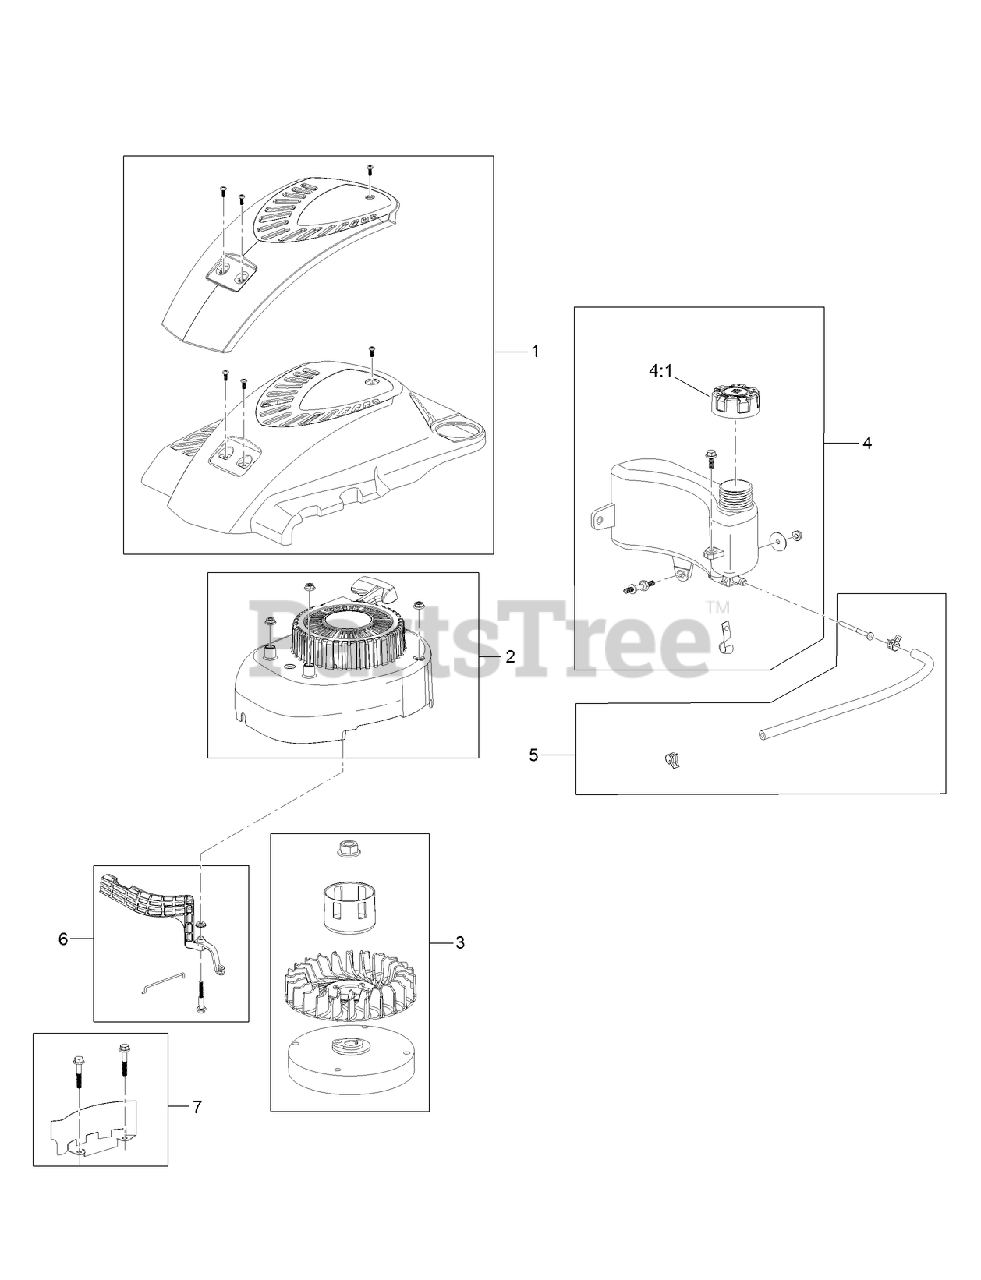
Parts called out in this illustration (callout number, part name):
1	SHROUD ASM
2	RECOIL AND BLOWER SHROUD KIT
3	FLYWHEEL AND FAN KIT
4	FUEL TANK KIT (CAP AND HARDWARE)
4:1	CAP-FUEL
5	FUEL LINE KIT
6	AIR VANE CHOKE KIT
7	FLYWHEEL SHIELD KIT
